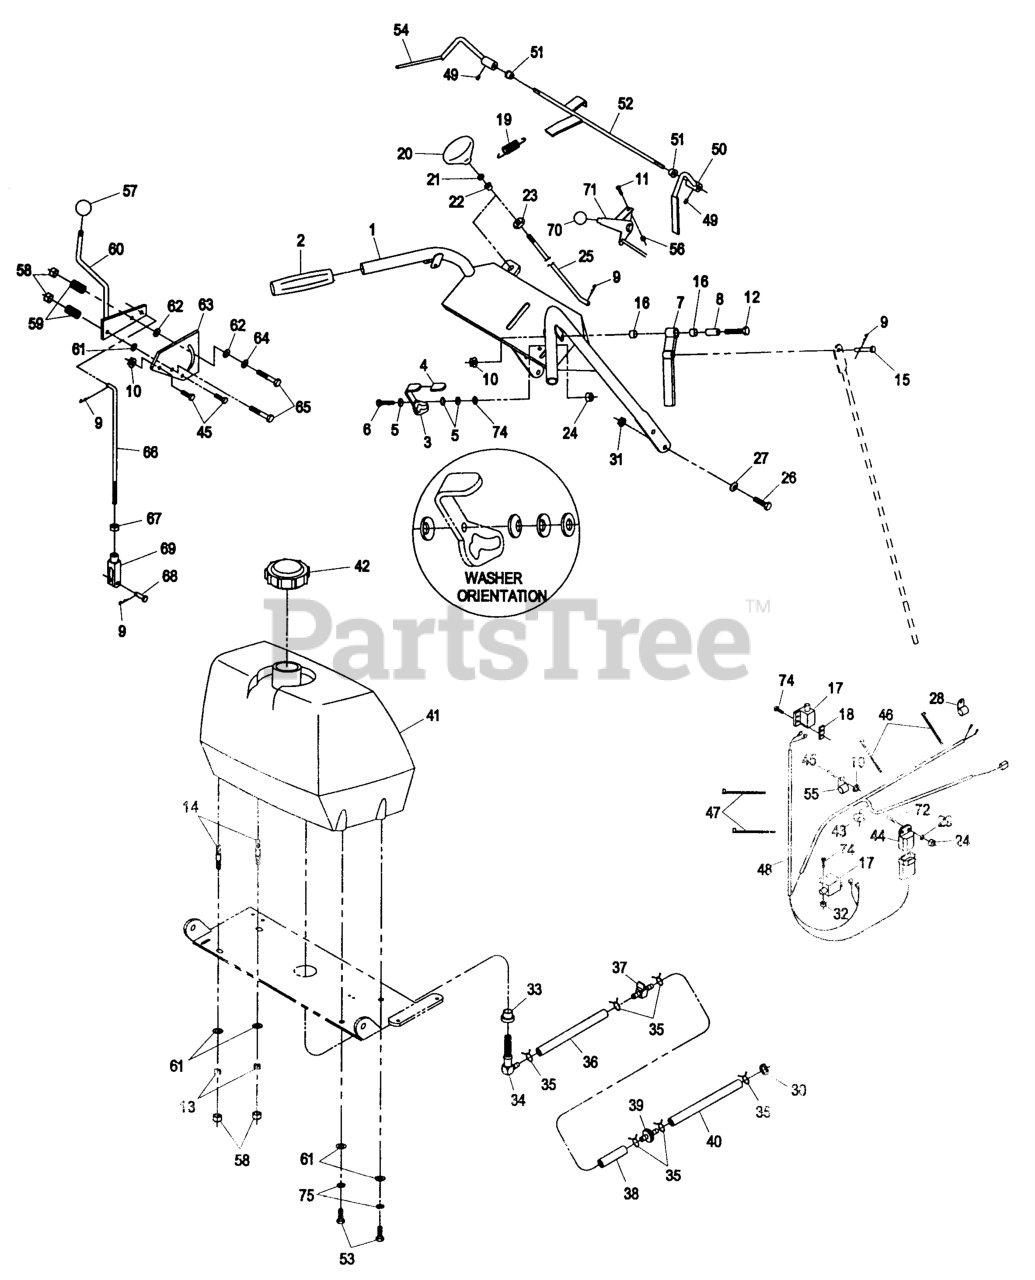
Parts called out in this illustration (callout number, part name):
4	GRIP-LATCH
5	WASHER-SPRING
8	BUSHING-LEVER, DRIVE
9	PIN-COTTER
11	BOLT-CARR
13	SPRING-TANK, FUEL
14	STUD
15	PIN-CLEVIS
16	BUSHING-SLEEVE
17	SWITCH-OPEN, NORMALLY
18	PLATE-TAPPED
19	SPRING-EXTENSION
20	KNOB-PUSH / PULL
22	BEARING-NYLON
23	NUT-PUSH
25	LINKAGE-BLADE
28	CLIP-LOOM
30	CLAMP-HOSE
32	NUT-SQH
34	ELBOW-TANK, FUEL
36	HOSE-FUEL
37	VALVE-FUEL
38	HOSE-LINE, FUEL
40	HOSE-LINE, FUEL
42	CAP-FUEL
43	GROMMET
44	MODULE-INTERLOCK
46	TIE-CABLE
47	TIE-PLASTIC
48	WIRHRNS,VH36" 14HP KAW
49	SCREW-SET
50	LEVER-RH
51	BUSHING-NYLON
52	WLD,ROD OPC
54	LEVER-LH
55	CLIP-LOOM
57	KNOB-BALL
59	SPRING-COMPRESSION
62	WASHER-FRICTION
63	PLATE-LEVER, SHIFTER
64	WASHER-FRICTION
66	ROD-CONTROL, SPEED
68	PIN-CLEVIS
69	YOKE-ADJUSTABLE
70	KNOB-BALL
71	CABLE,THROTTLE CONTROL
75	WASHER-LOCK
